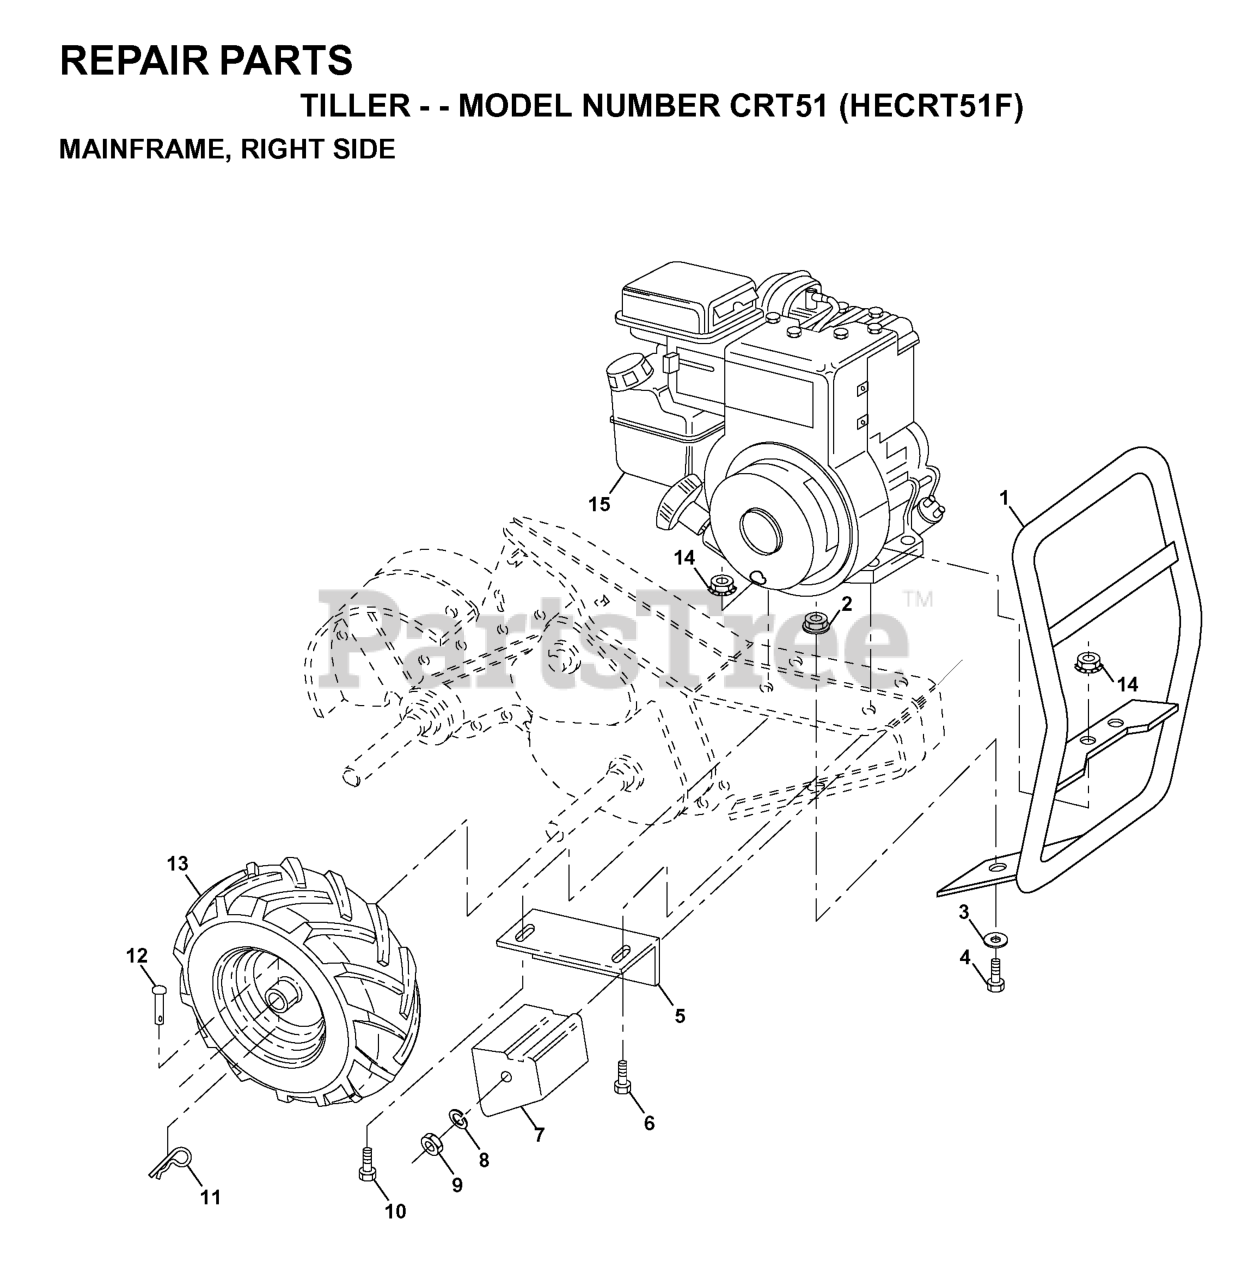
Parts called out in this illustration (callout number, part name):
1	BUMPER
2	LOCKNUT-FLANGE 5/16-18
3	WASHER
4	BOLT
5	DNO BRACKET RH CRT
6	Bolt Fin Hex 5/16 - 18 Unc x 2 Gr. 2
7	COUNTERWEIGHT, RH
8	WASHER, LOCK 3/8
9	NUT.HEX.3/8-16UNC
10	BOLT
11	RETAINER M
12	RIVET,DRILLED
13	TIRE.16X4-8.CHEVRON.TILLER
14	NUT
532124366	RIM
532124718	VALVE STEM LT
